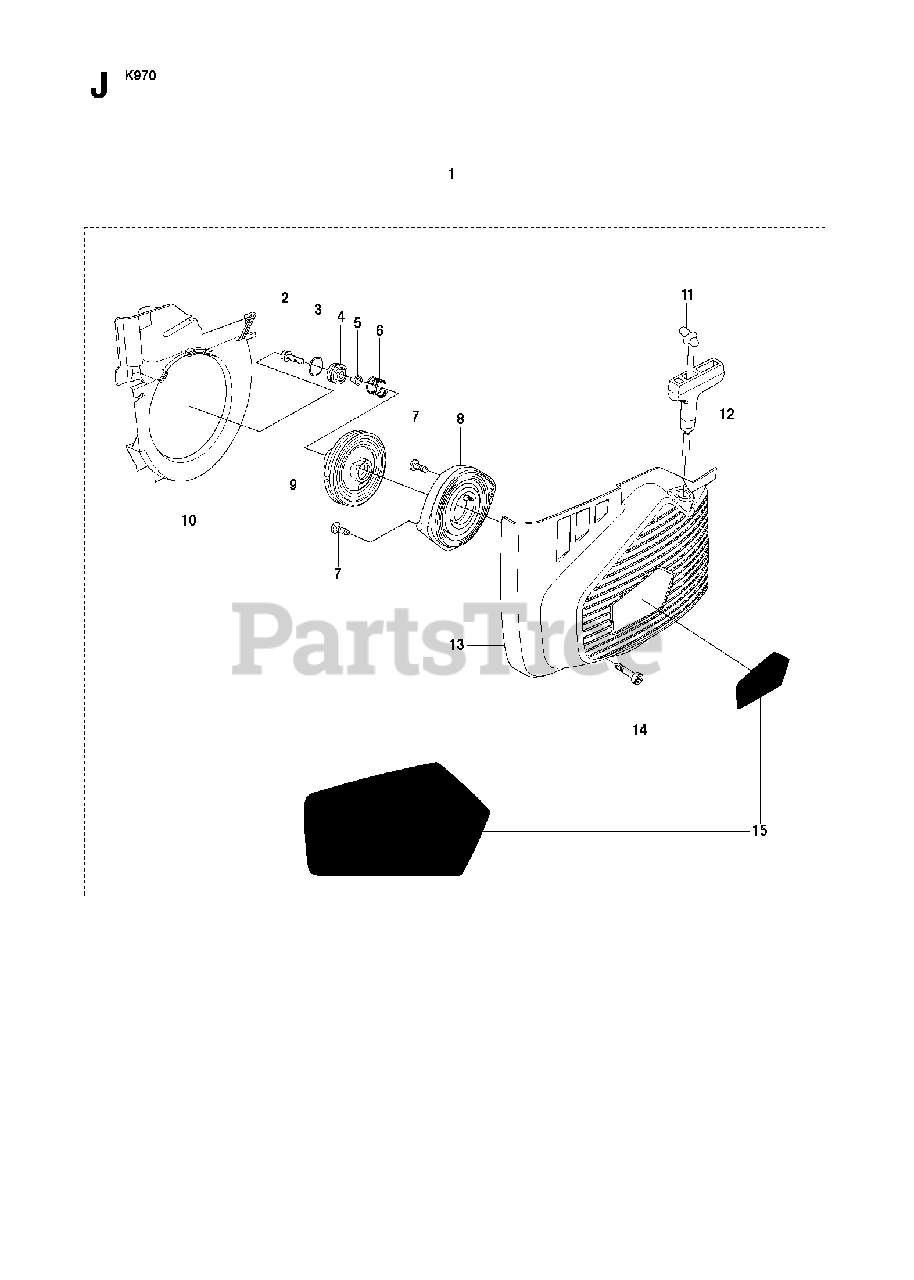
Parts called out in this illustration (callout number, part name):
1	STARTER ASSY
2	SCREW IHSCT
4	GROMMET
5	SPACING SLEEVE
6	COMPRESSION SPRING
7	SCREW CCRPANT
8	RECOIL SPRING
9	STARTER PULLEY
10	AIR CONDUCTOR
11	STARTER CORD
12	STARTER HANDLE
13	STARTER COVER
14	SCREW ITXSCM
